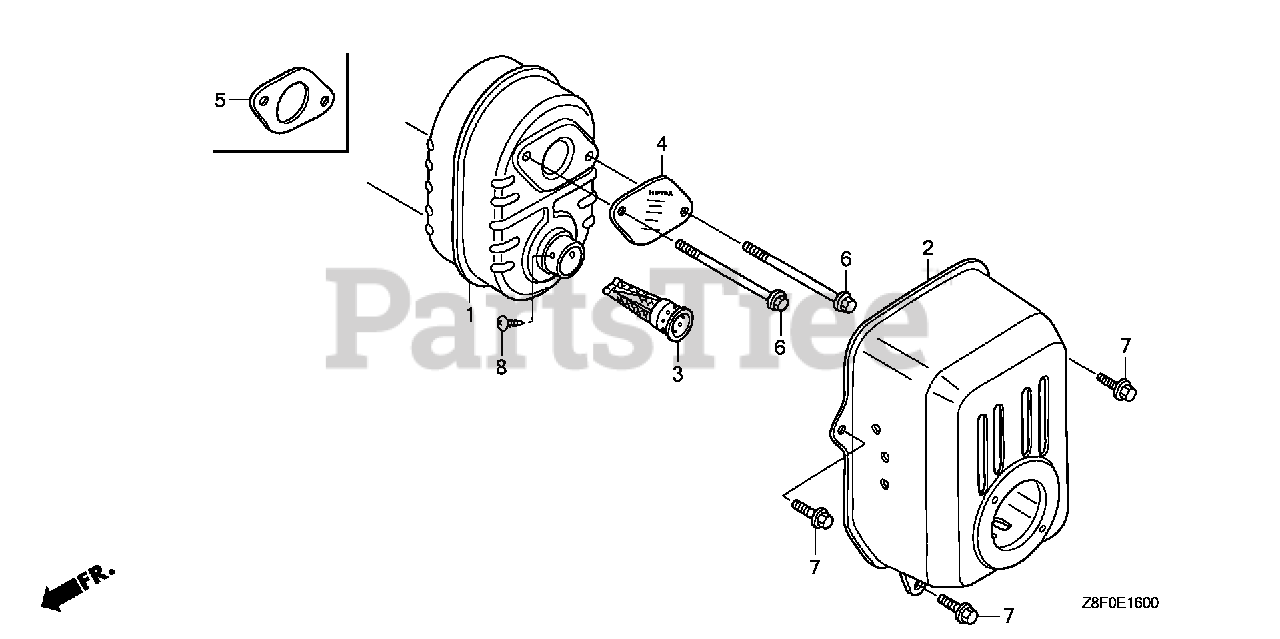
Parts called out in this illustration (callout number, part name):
1	MUFFLER
2	PROTECTOR, MUFFLER
3	ARRESTER, SPARK (TO 1207644)
4	PLATE, ARRESTER NUMBER (TO INSTALL OPTIONAL SPARK ARRESTER)
5	GASKET, MUFFLER
6	BOLT, FLANGE (6X79) (CT200)
7	BOLT, FLANGE (6X13)
7	BOLT, FLANGE (6X12) (CT200)
8	SCREW, TAPPING (4X6) (TO INSTALL OPTIONAL SPARK ARRESTER)
